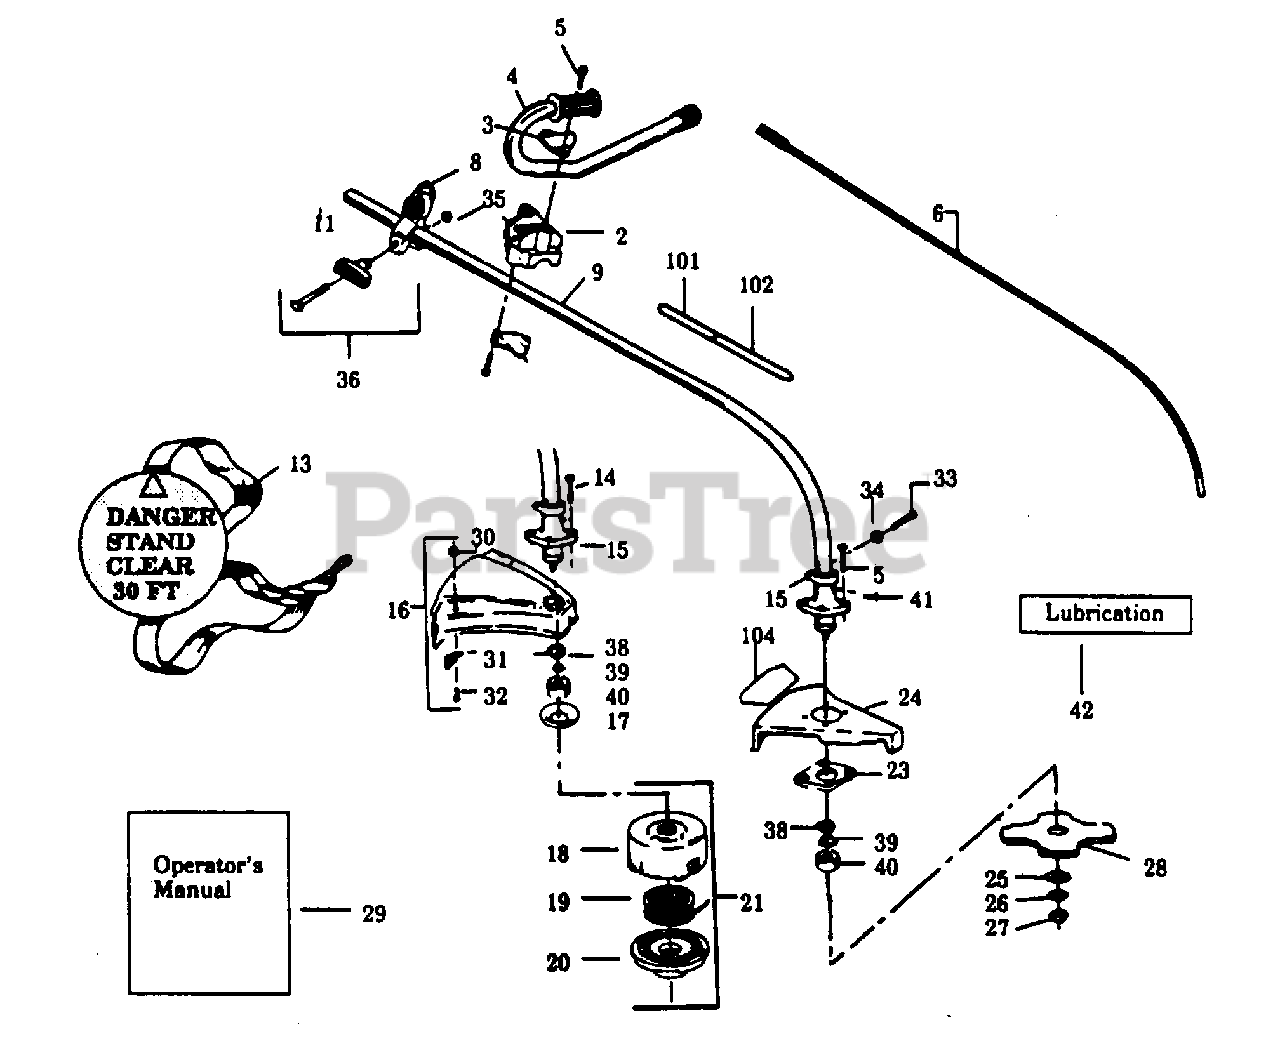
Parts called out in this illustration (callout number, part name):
2	Handlebar Clamp
3	Handlebar Bracket
4	Handlebar
5	Screw 1/4 - 20 x 1- 1/16
6	Drive Shaft (Flex)
8	Clamp Harness Ass'y.
9	Drive Shaft Housing
13	Shoulder Strap
14	Screw 1/4 - 10 x 1 - 1/16
15	Bearing Housing Ass'y.
16	Shield Kit Ass'y. (Incl. #14 30 31, 32)
17	Grass Washer
18	Hub Ass'y.
19	Spool w/Line
21	Cutting Head Ass'y. (Incl. #18, 19, 20)
23	Shield Retention Plate
26	Washer
28	Weed Blade
29	Operator's Manual
30	Locknut
31	Line Limiter
32	Screw # 10 - 24 x 5/8
33	Screw 1/4 - 20 x 1
35	Locknut 1/4 - 20
36	"T" Handle Kit
38	Retaining Ring
40	Dust Cup
42	Shaft Lubrication
101	Decal - Shaft Warning (Upper)
102	Decal - Shaft Warning (Lower)
104	Decal - Blade Direction
